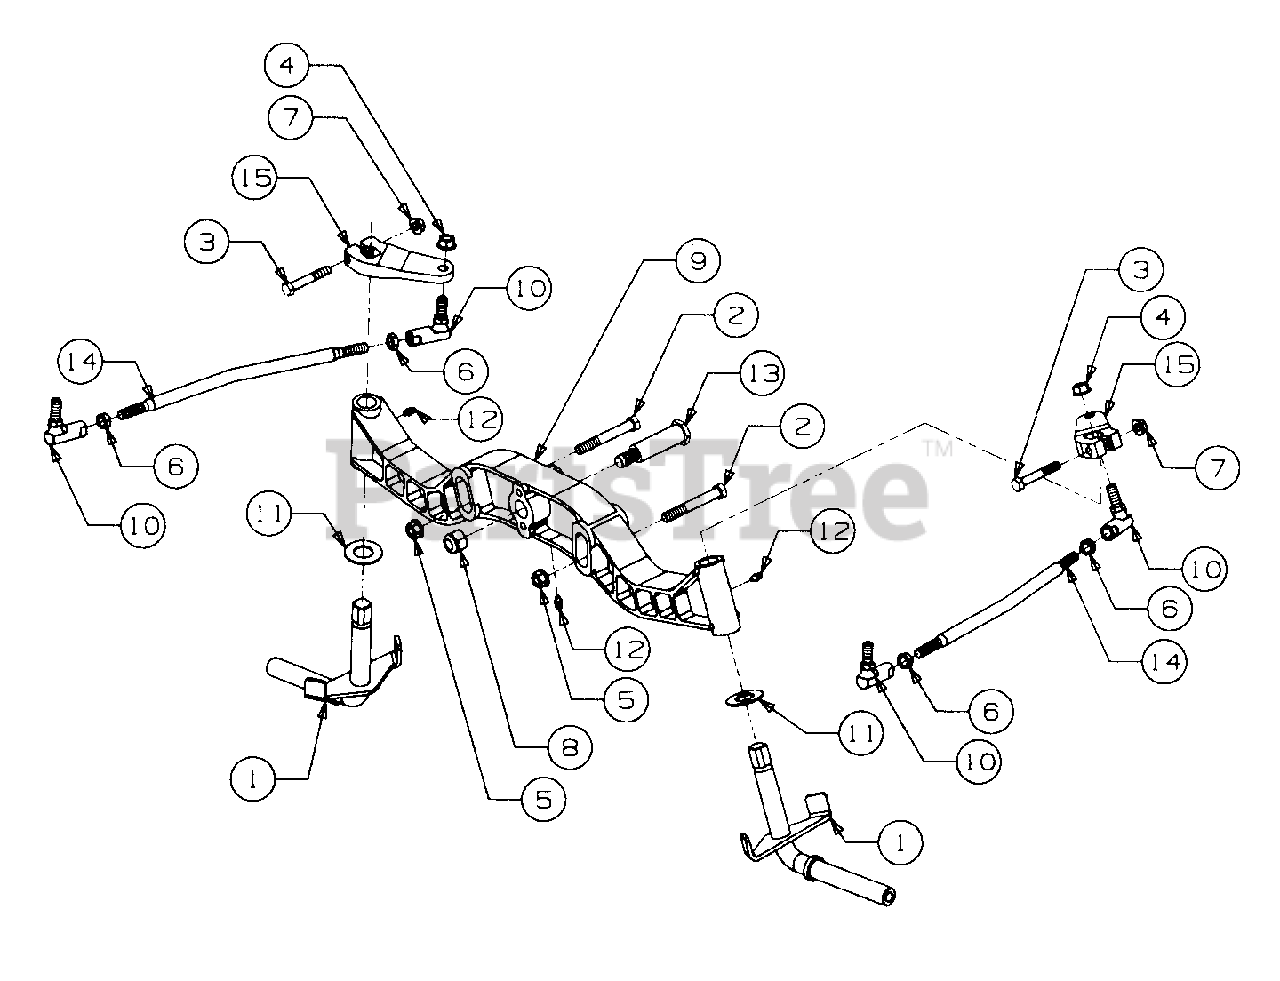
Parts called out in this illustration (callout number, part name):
1	Knuckle Assy, Steering
2	Screw, Hex Cap, 3/8-16 x 2.75 Lg GR8
3	Screw, Hex Cap, 5/16-18 x 2.0 Lg GR2
4	Nut, Hex Lock, 3/8-24 GR5
5	Nut, Hex Flanged Lock, 3/8-16
6	Nut, Hex Jam, 3/8-24 GR5
7	Nut, Hex Flange Top Lock, 5/16-18
8	Nut, Hex Top Nylon Lock, 1/2-13
9	Axle, Front Pivot
10	Joint, Ball, 3/8-24
11	Washer, Flat, .760 x 1.49 x .06 Thk Hdn
12	Fitting, Lube, 3/16 Drive Type
13	Bolt, Pivot Shoulder, 3/4 Dia x 2.23 Lg
15	Arm, Steering
